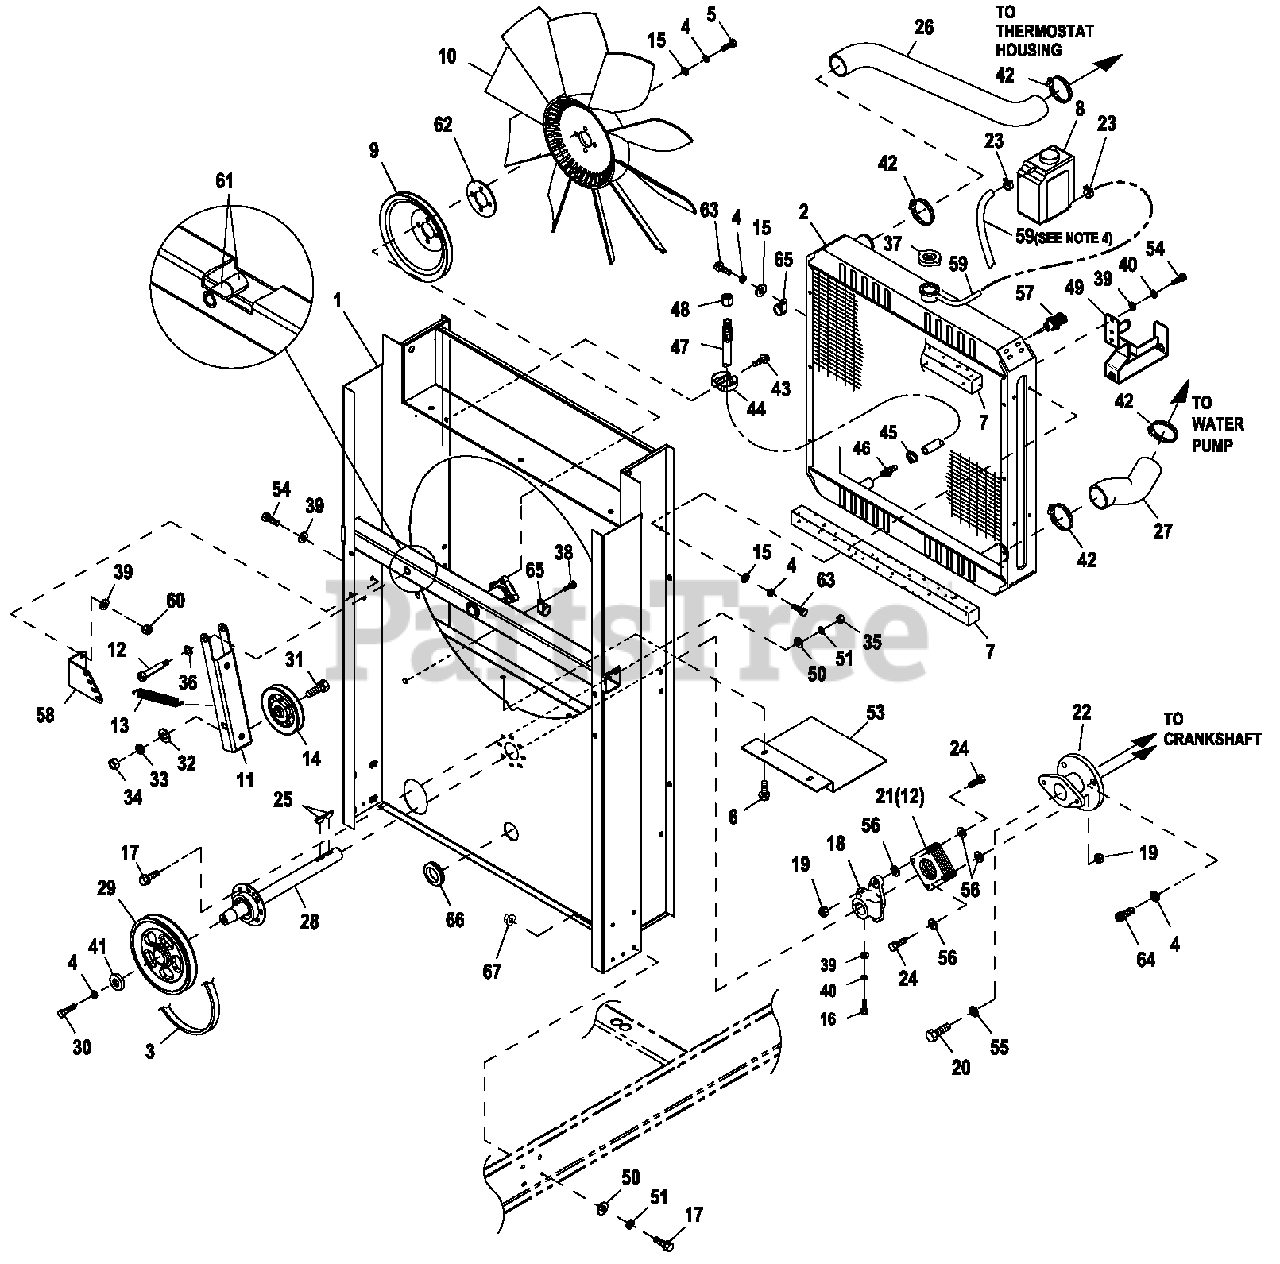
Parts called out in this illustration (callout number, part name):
1	WELDMENT RADIATOR SUPPORT C5
2	RADIATOR 680X680X 70 CPL
3	V-BELT 31/64" X 62-3/8"
4	WASHER LOCKM10
5	SCREW HHC M10-1.5X30C10.9
6	SCREW THF M6-1 X 16 N WA Z/JS
7	TAPE FOAM 1 X 1 (26.75' LG)
8	TANK COOLANT RECOVERY
9	PULLEY FAN V-GROOVE 9"
10	FAN 26" LH ROTATION
11	ARM BELTTENSIONER
12	SHOULDER BOLT 1/2 X 2-1/4"
13	SPRING TENSION CPL
14	PULLEY V-BELT 4" FLANGED
15	WASHER FLAT 3/8-M10 ZINC
16	SCREW HHC M8-1.25X45 C8.8
17	SCREW HHFCM6-1.0X20 G8.8
18	HUB FLEX PLATE
19	NUT HEX LOCK 5/16-24 NY INS
20	SCREW HHC M12-1.5X60 G8.8
21	DISK FLEX
22	COUPLING HUB FLEX (MACH)
23	CLAMP HOSE BAND 1/4
24	SCREW HHC 5/16-24X1.124
25	KEY WOODRUFF 4 X19D
26	HOSE RADIATOR UPPER CPL
27	HOSE LOWER RAD CPL C5 6.8L
28	ASSY BRG/SHAFT CPL FANDRIVE
29	PULLEY 6.5" DIA MACHINED (6.8L 100KW)
30	SCREW HHC M10-1.5X30 G8.8
31	SCREW HHC 1/2-13X2" G8
32	WASHER FLAT 1/2 ZINC
33	WASHER LOCK 1/2
34	NUT HEX 1/2-13 STEEL
35	NUT HEX M6 X 1.0 G8 YEL CHR
36	WASHER NYLON .50X .87X .06
37	CAP RADIATOR 13 PSI
38	SCREW HHTTM6-1.0X 16 ZYC
39	WASHER FLAT 5/16-M8 ZINC
40	WASHER LOCK M8-5/16
41	SPACER 5X 1.5 X .25 STL/ZINC
42	CLAMP HOSE #28 1.32-2.25
43	SCREW HHTT M4-0.7 X 8 BP
44	SPRING CLIP HOLDER .37- 62
45	CLAMP HOSE .38-.87
46	BARBED STR 3/8 NPT X 3/8
47	HOSE DRAIN ASSY 28"
48	CAP HEX 1/4 NPT BRASS
49	BRACKET COOLANT TANK
50	WASHER FLAT 1/4-M6 ZINC
51	WASHER LOCK M6-1/4
53	SHIELD RADIATOR
54	SCREW HHC M8-1.25X20 G8.8
55	WASHER LOCK M12
56	WASHER FLEX (THIN)
57	PROBE COOLANT LEVEL 3/8-18NPTF
58	BRACKET TENSIONER SPRING
59	HOSE 9/32 ID (43'LG)
60	NUT HEX LOCK M8-1.25 NY INS
61	BEARING SLEEVE 1/2/X 3/4X1
62	SPACER CPL COOLING FAN 1/8"
63	SCREW HHC M10-1.5X20 C8.8
64	SCREW SHC M10-1.5X 30 C12.9
65	CLAMP STL/VNL .62X.406Z
66	GROMMET 1.37 X .06X 1.00
67	NUT FLANGE M6-1.0 NYLOK
